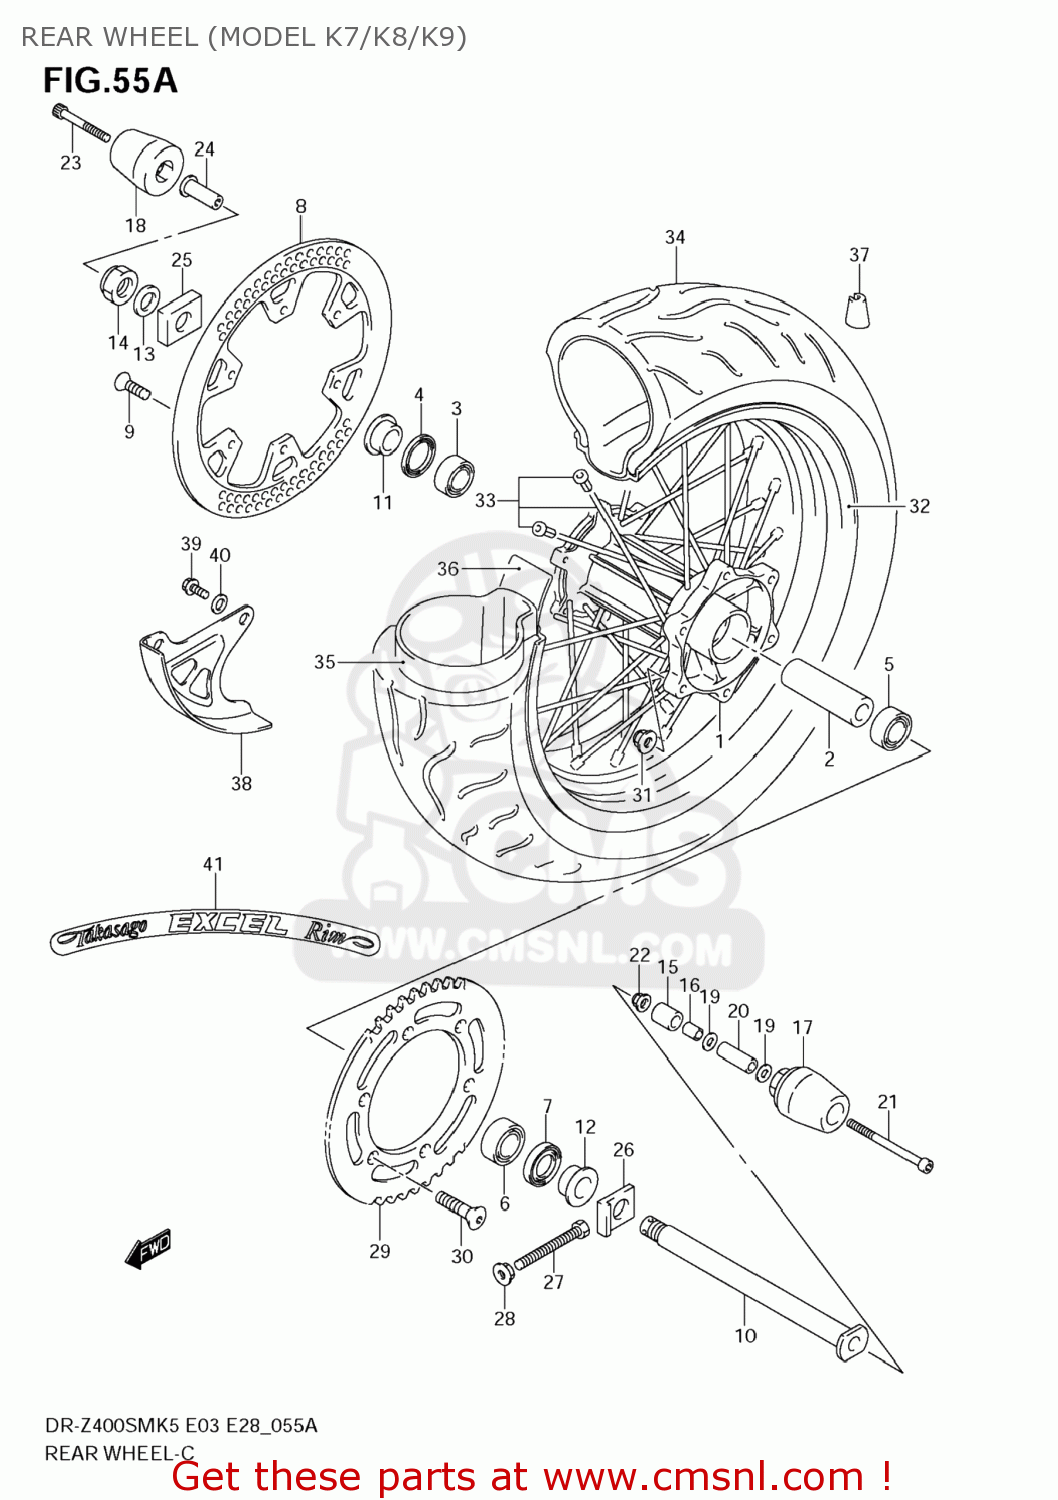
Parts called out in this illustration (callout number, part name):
1	HUB,RR WHEEL
2	SPACER,RR HUB BEARING
3	BEARING
4	SEAL(29X42X6)
5	BEARING
6	BEARING
7	SEAL,OIL(29X47X6)
8	DISC,RR BRAKE
9	SCREW(6X18)
10	AXLE,RR
11	SPACER,RR AXLE
12	SPACER,RR AXLE
13	WASHER(19X32X3.2)
14	NUT
15	EXPANDER,FR AXLE SLIDER,R
16	SPACER(5.5X8X10.5)
17	SLIDER,RR AXLE,L
18	SLIDER,FR AXLE,L
19	WASHER(5.5X12X0.8)
20	SPACER(5.5X9.5X26)
21	BOLT(5X65)
22	NUT
23	BOLT
24	NUT
25	ADJUSTER,CHAIN,R
26	ADJUSTER,CHAIN,L
27	BOLT(8X50)
28	NUT
29	SPROCKET,RR(NT:41)
30	BOLT(8X30.5)
31	NUT
32	RIM,RR WHEEL(17XMT4.50 AL)(BLK
33	SPOKE SET,RR WHEEL
34	TIRE,RR(140/70R17M/C 66H)
35	TUBE ASSY,WHEEL INNER
36	PROTECTOR,WHL INR TUBE
37	BALANCER,WHEEL(15G)
38	COVER,REAR DIS
39	BOLT(6X10)
40	WASHER
41	EMBLEM SET,EXCEL
